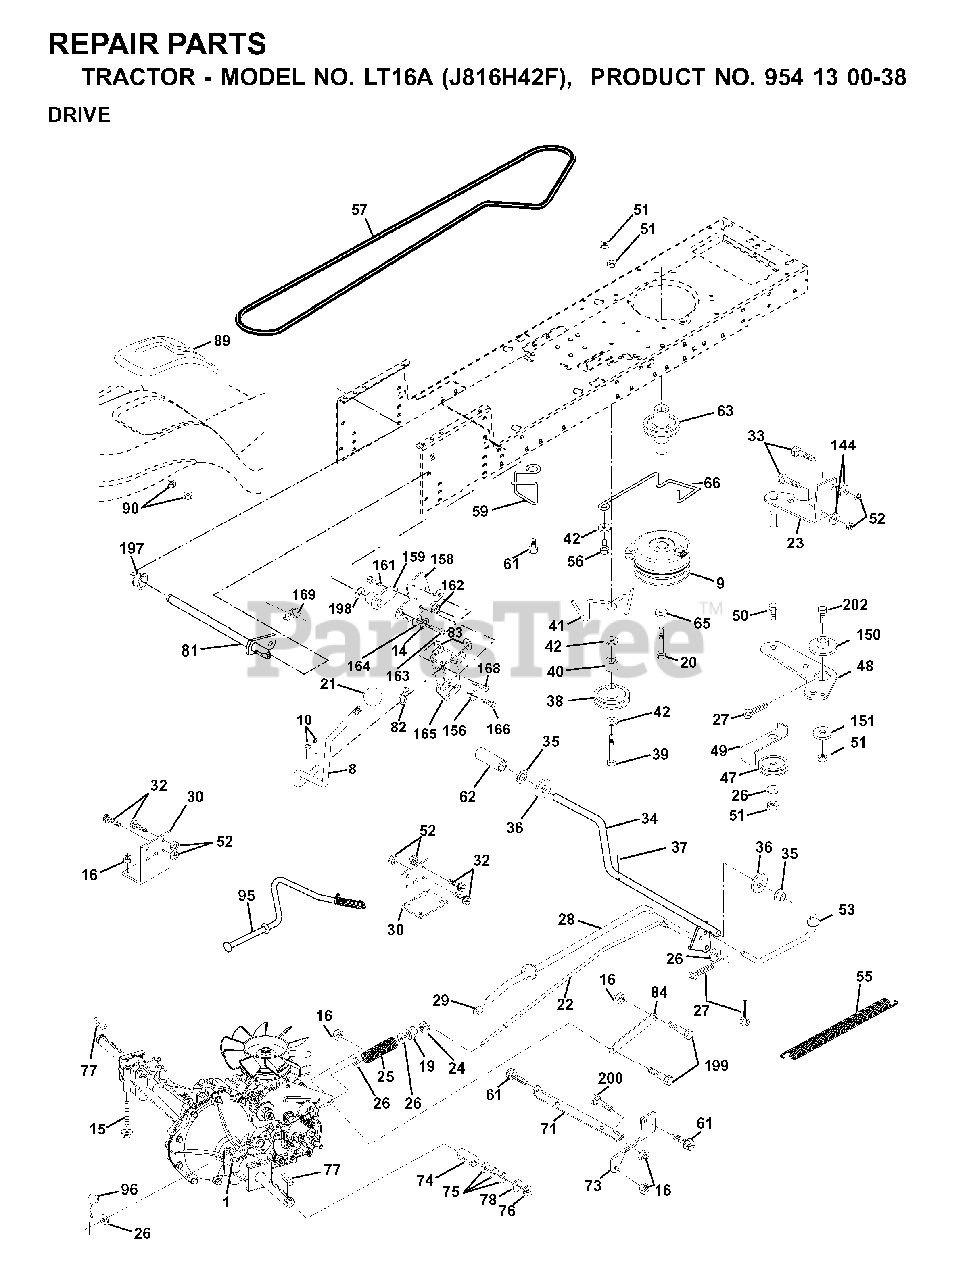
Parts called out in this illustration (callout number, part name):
8	ROD SHIFT FENDER ADJUST STLT
9	CLUTCH, ELECTRIC
10	PIN COTTER
14	LOCKWASHER
15	BOLT HEX 5/16-18 GR 5
16	NUT.71038.31-18.HEX.NYLOCK
19	NUT
20	BOLT HEX
21	PISTOL KNOB
22	ROD BRAKE HYDRO
24	NUT
25	SPRING ROD LT
27	COTTER PIN
28	ROD BRAKE PARK LT
29	PLUNGER CAP
30	BRKT, TRNSXLE MNT 20"
32	BOLT
33	BOLT
34	SHAFT, FOOT PEDAL
35	BEARING.NYLON
36	WASHER LT
37	DRIVE PIN
38	FLAT IDLER PULLEY
41	KEEPER.BELT.IDLER.FLAT
42	WASHER
47	IDLER PULLEY
48	BELLCRANK, CLUTCH
49	RETAIN BELT
50	BOLT
51	LOCKNUT
52	LOCKNUT
53	LINK, CLUTCH LT
55	SPRING, RETURN LT
59	KEEPER, BELT CENTER
61	SCREW 3/8-16X3/4
62	PEDAL COVER T
63	PULLEY, CLUTCH ELECT EVX
65	LOCKWASHER
66	KEEPER BELT ENGINE
71	STRAP TORQUE LH HYDRO
73	STRAP TORQUE RH HYDRO
76	E-RING LT
77	SQUARE KEY
81	SHAFT ASM CROSS TAPERED
82	SHIFT SPRING
83	WASHER
84	LINK TRANSAXLE
95	CONTROL ASM. BYPASS HYDRO
96	RETAINER M
144	WASHER
150	BUSHING.BELLCRANK.GRD.DR
151	WASHER 12/32X2X10GA
156	WASHER.SRRTD.5/16
158	BRACKET
159	HUB
161	BOLT
162	NUT.CROWNLOCK.1/4
165	RP BRACKET
168	BOLT.SHOULDER.5/16-18X
169	PLATE.FASTENING.CROSS.SHAFT
197	NYLINER SNAP 5/8" ID
198	WASHER.NYL.7/8IDX.105"HYD CR
199	BOLT SHOULDER 5/16-18 UNC
200	BOLT
202	BOLT.3/8-16X1.50
